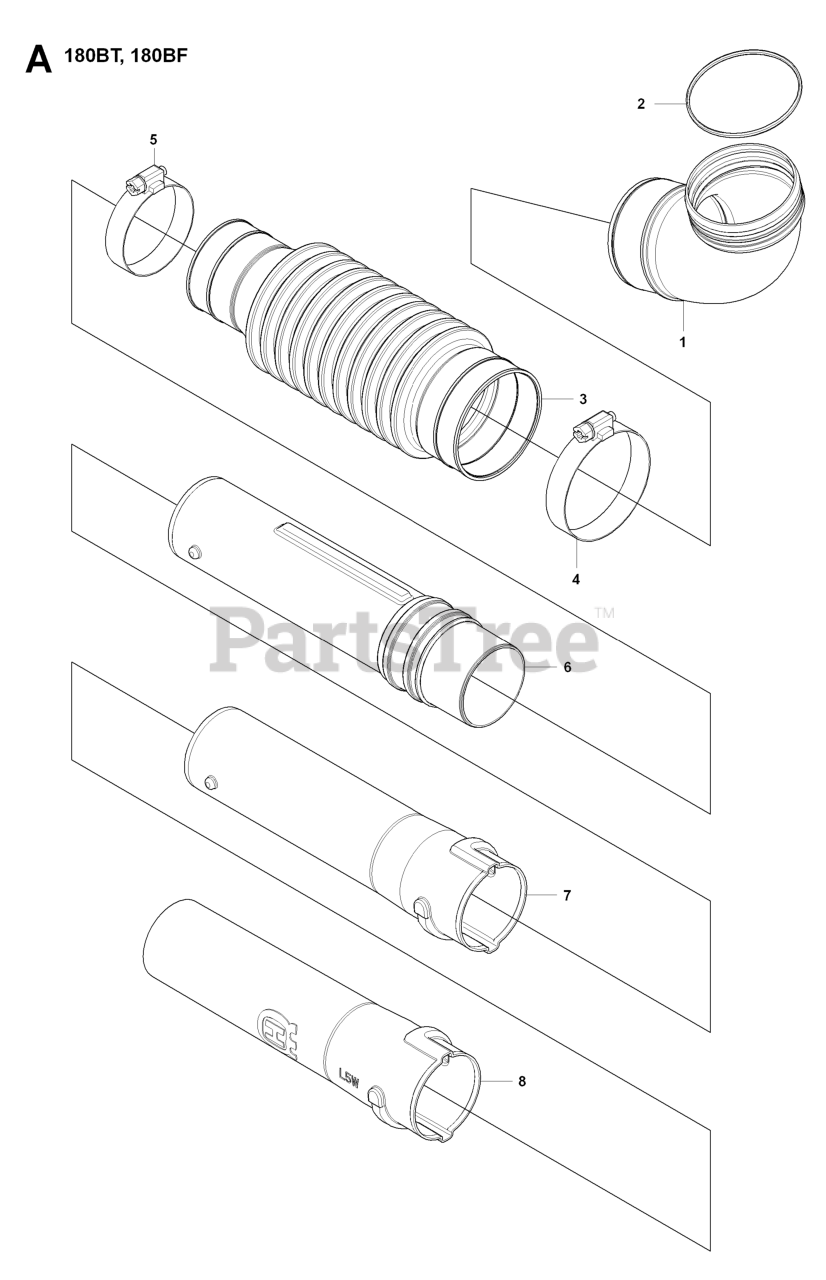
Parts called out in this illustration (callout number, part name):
4	CLAMP(F115)
5	CLAMP(F96)
6	SWIVEL JOINT
7	PIPE,STRAIGHT
